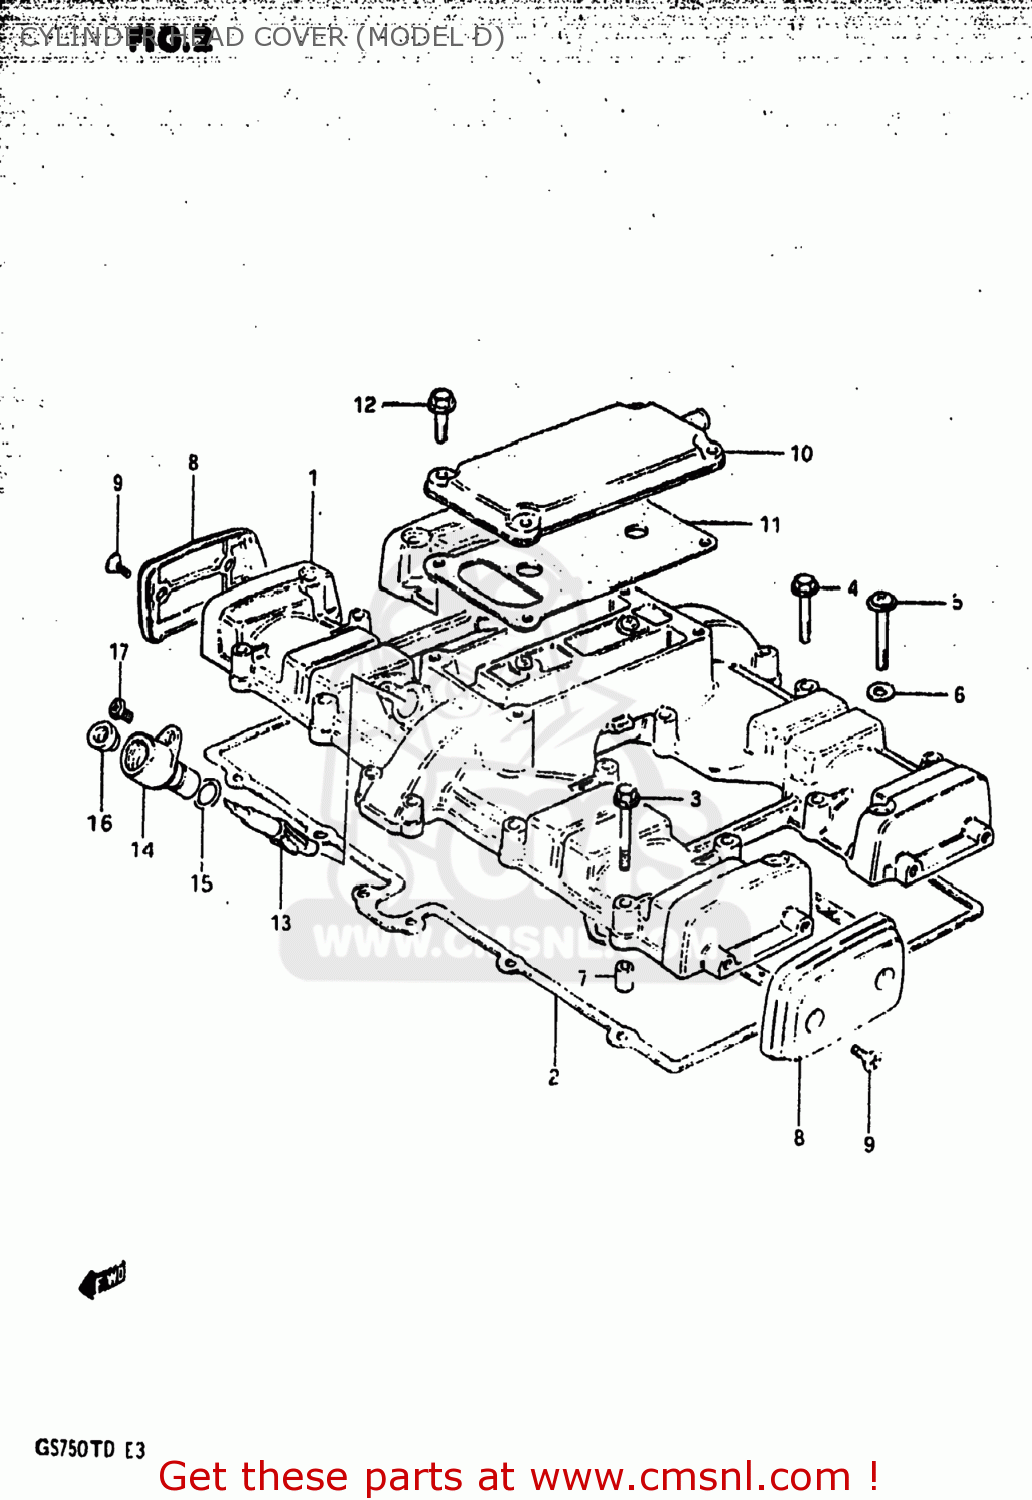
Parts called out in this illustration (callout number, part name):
1	COVER,CYLINDER HEAD
2	GASKET,CYLINDER HEAD COVER
3	BOLT (6X40)
4	BOLT
5	SCREW 6X40
6	WASHER
7	PIN(6.2X8X11)
8	CAP,CYLINDER HEAD COVER
9	SCREW(5X12)
10	COVER,BREATHER
11	GASKET (MCA)
12	BOLT
13	GEAR,TACHOMETER DRIVEN
14	SLEEVE,TACHOMETER DRIVE GEAR
15	SEAL,TACHOMETER DRIVEN
16	SEAL,OIL(5X12X8)
17	SCREW(5X12)
